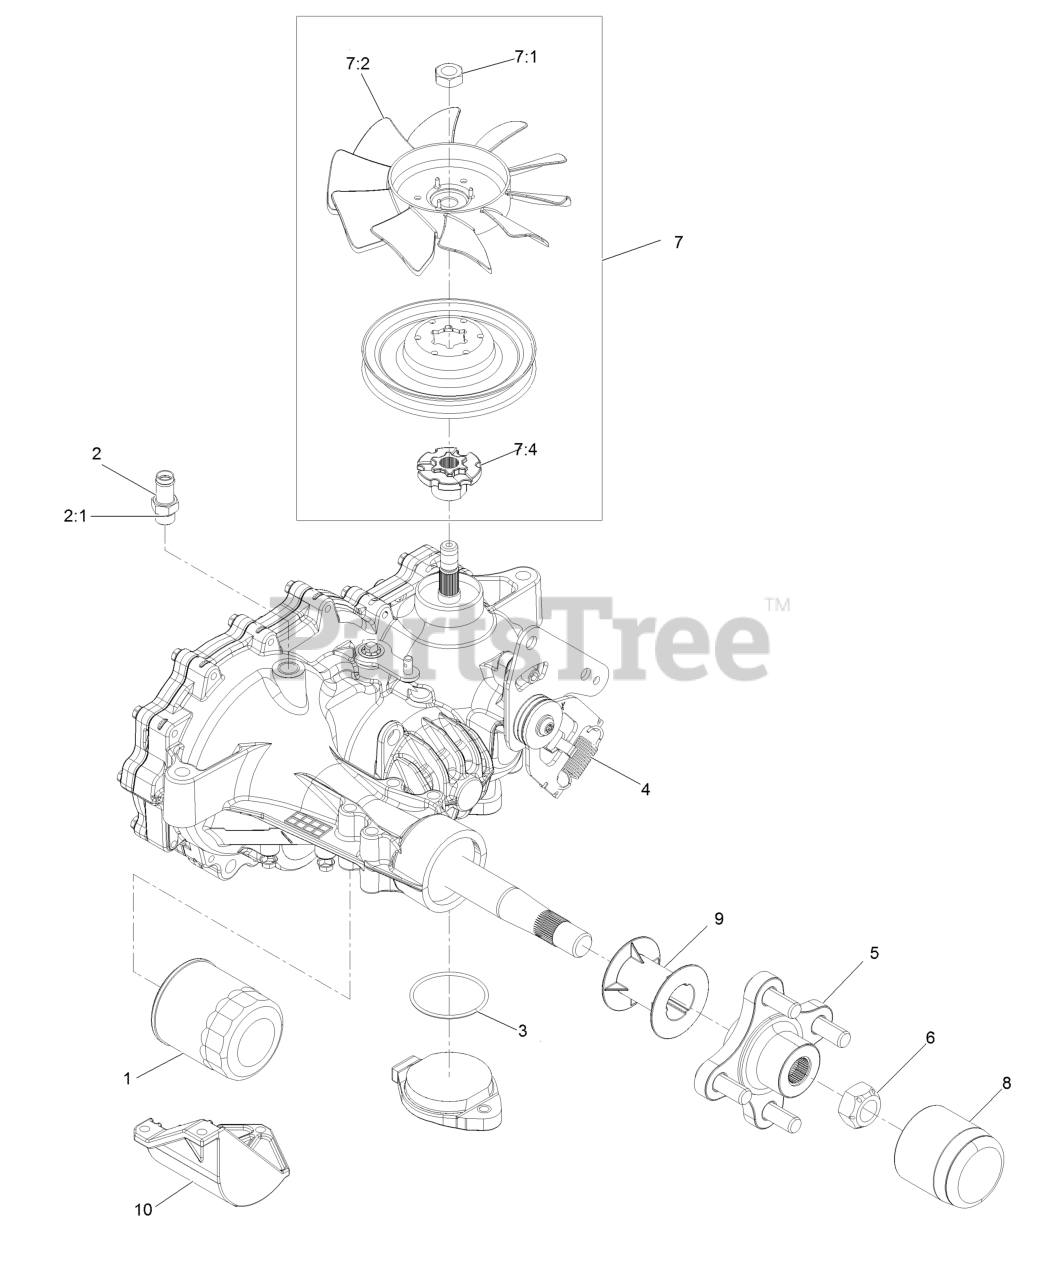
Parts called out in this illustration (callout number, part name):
1	Element-Oil Filter, HYD
2	Adapter-Straight
2:1	O-Ring
3	O Ring-Seal
4	Spring-Extension
5	Hub-Offset
6	Nut-Hub
7	Fan And Pulley Kit
7:4	Hub-Pulley
8	Cap-Axle, Long
9	Tube-Axle
10	Guard-Filter, RH
99	Seal Kit
99	Brake Shaft Seal Kit
